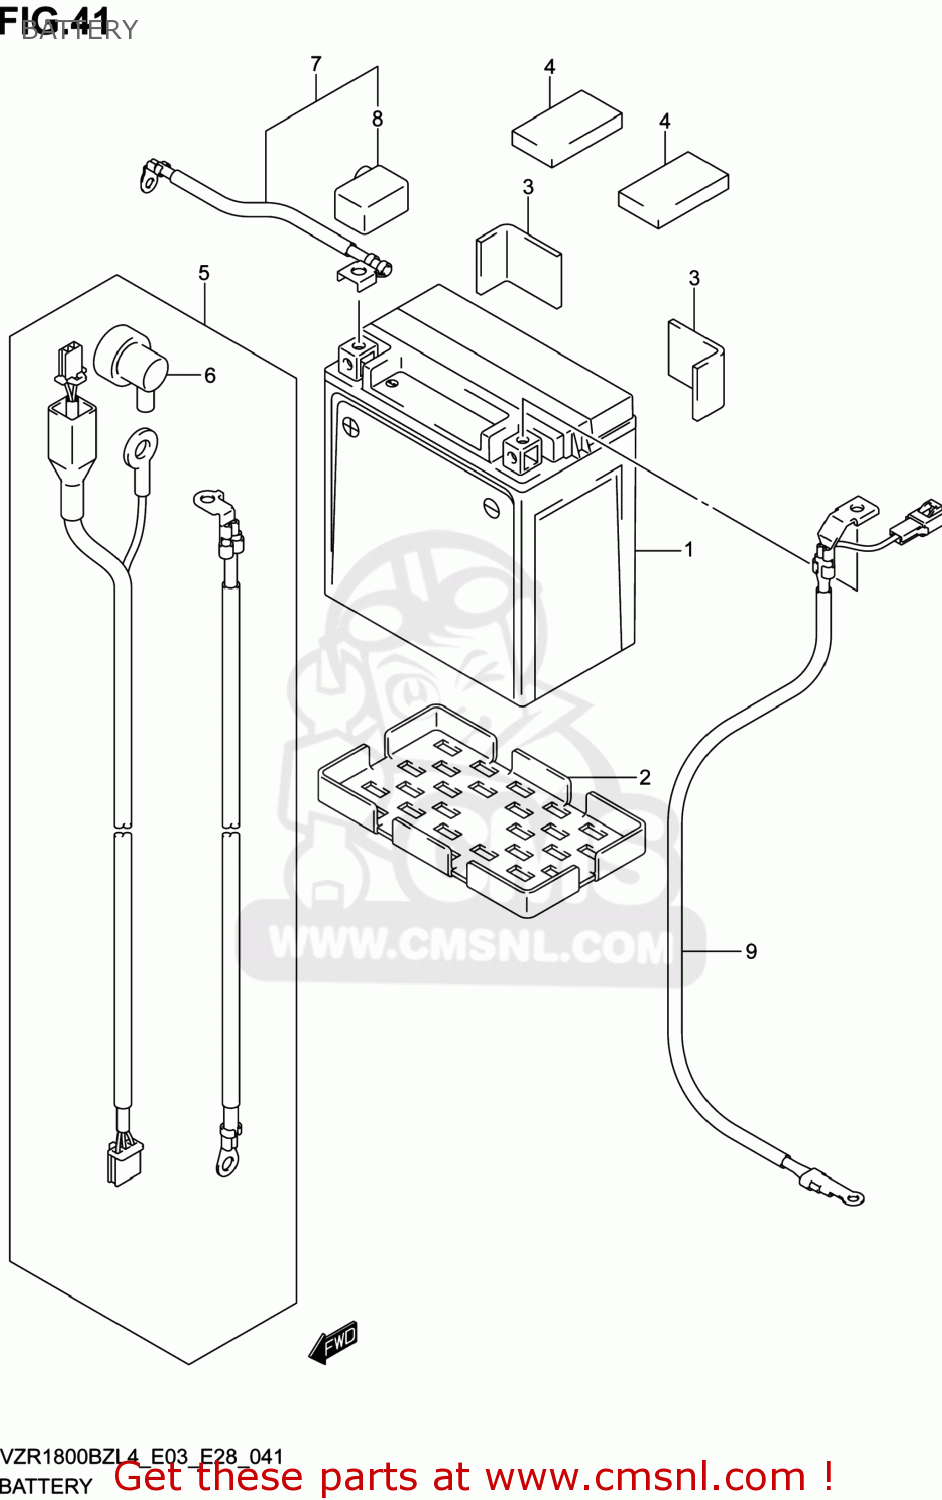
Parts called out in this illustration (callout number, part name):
1	BATTERY(FTZ16-BS,12V18.9AH)
2	PROTECTOR,BATTERY
3	CUSHION(30X50X3)
4	PROTECTOR,BATTERY(70X100X6)
5	WIRE,STARTER MOTOR LEAD
6	CAP,OIL PRESSURE SWITCH
7	WIRE,BATTERY PLUS LEAD
8	CAP,BATTERY PLUS
9	WIRE,BATTERY MINUS LEAD
